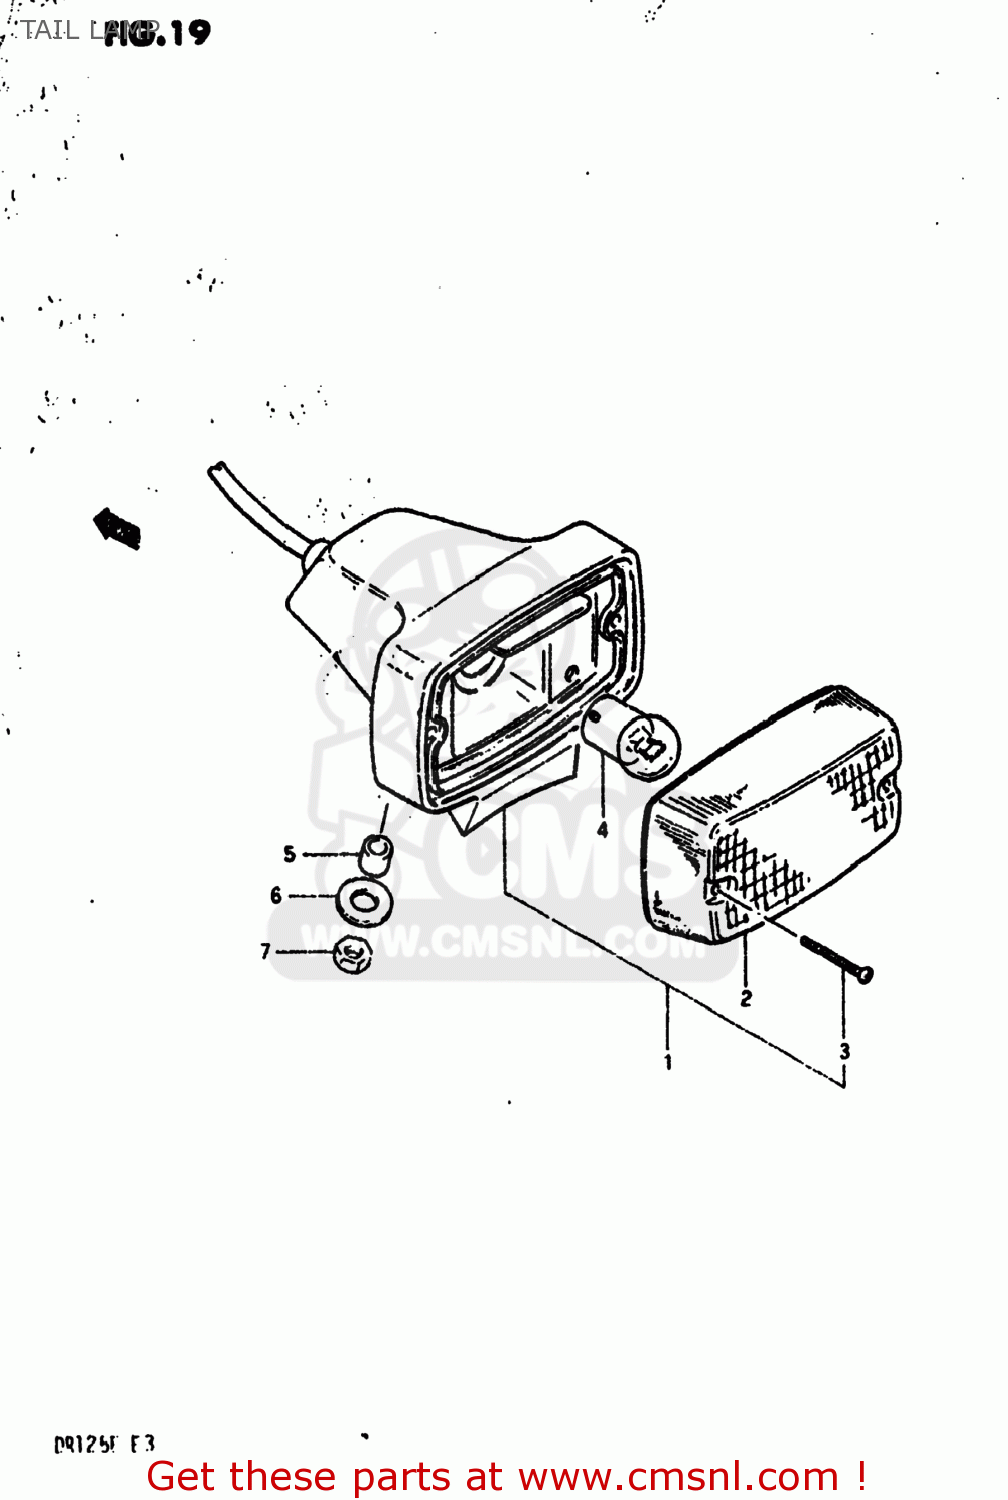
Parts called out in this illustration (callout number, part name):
1	LAMP ASSEMBLY,TAIL
2	LENS
3	SCREW,REAR COMBINATION LAMP LENS
4	BULB(6V5W,TOKAI DENSO)
5	SPACER (6.3X9.1X6.7)
6	WASHER
7	NUT
